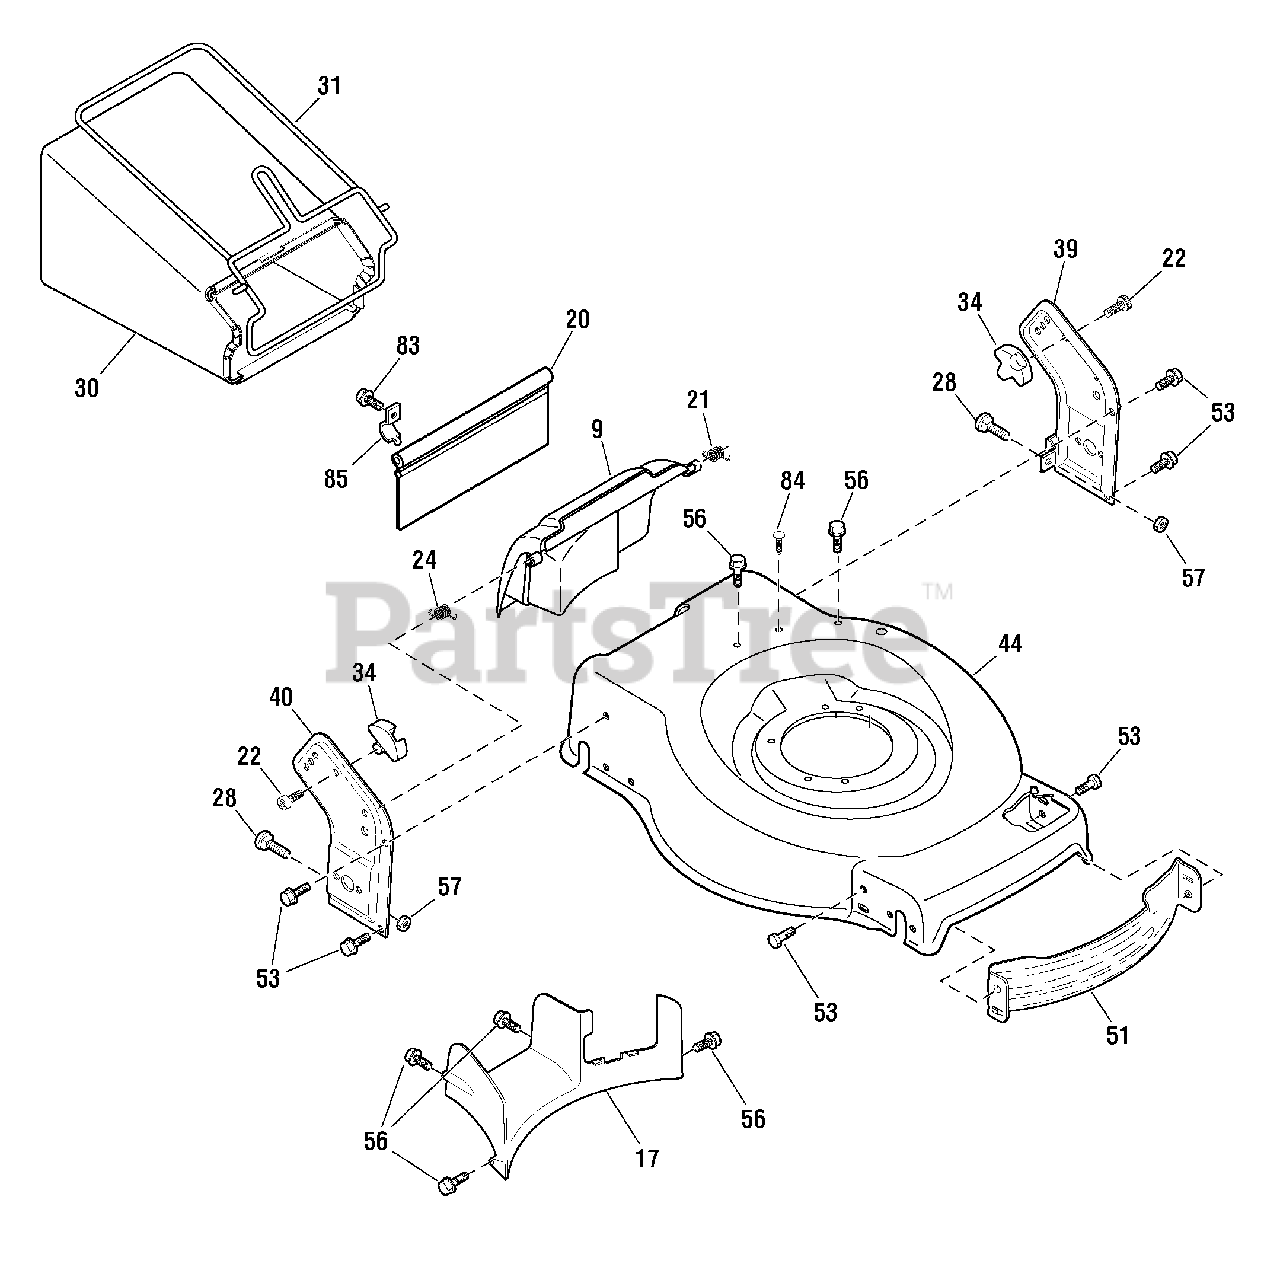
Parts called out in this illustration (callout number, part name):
9	REAR DOOR ASSEMBLY
17	BAFFLE, Rear
20	SKIRT, Rear
21	SPRING, Rear Door, Left
22	SCREW, Panhead Torx, #20
24	SPRING, Rear Door, Right
28	BOLT, Carriage, 5/16-18 x 5/8
30	GRASS BAG
31	FRAME, Grass Bag
34	BRACKET, Grass Bag
39	BRACKET, Handle, Left
40	BRACKET, Handle, Right
44	KIT, Mower Deck, 22"
51	BAFFLE, Front
53	SCREW, 5/16-18
56	SCREW, Hex Washer head, #13 x 3/4
57	NUT, Hex
83	SCREW, Hex Washer Head
84	FASTENER, Push
85	BRACKET, Mounting, Rear Skirt
